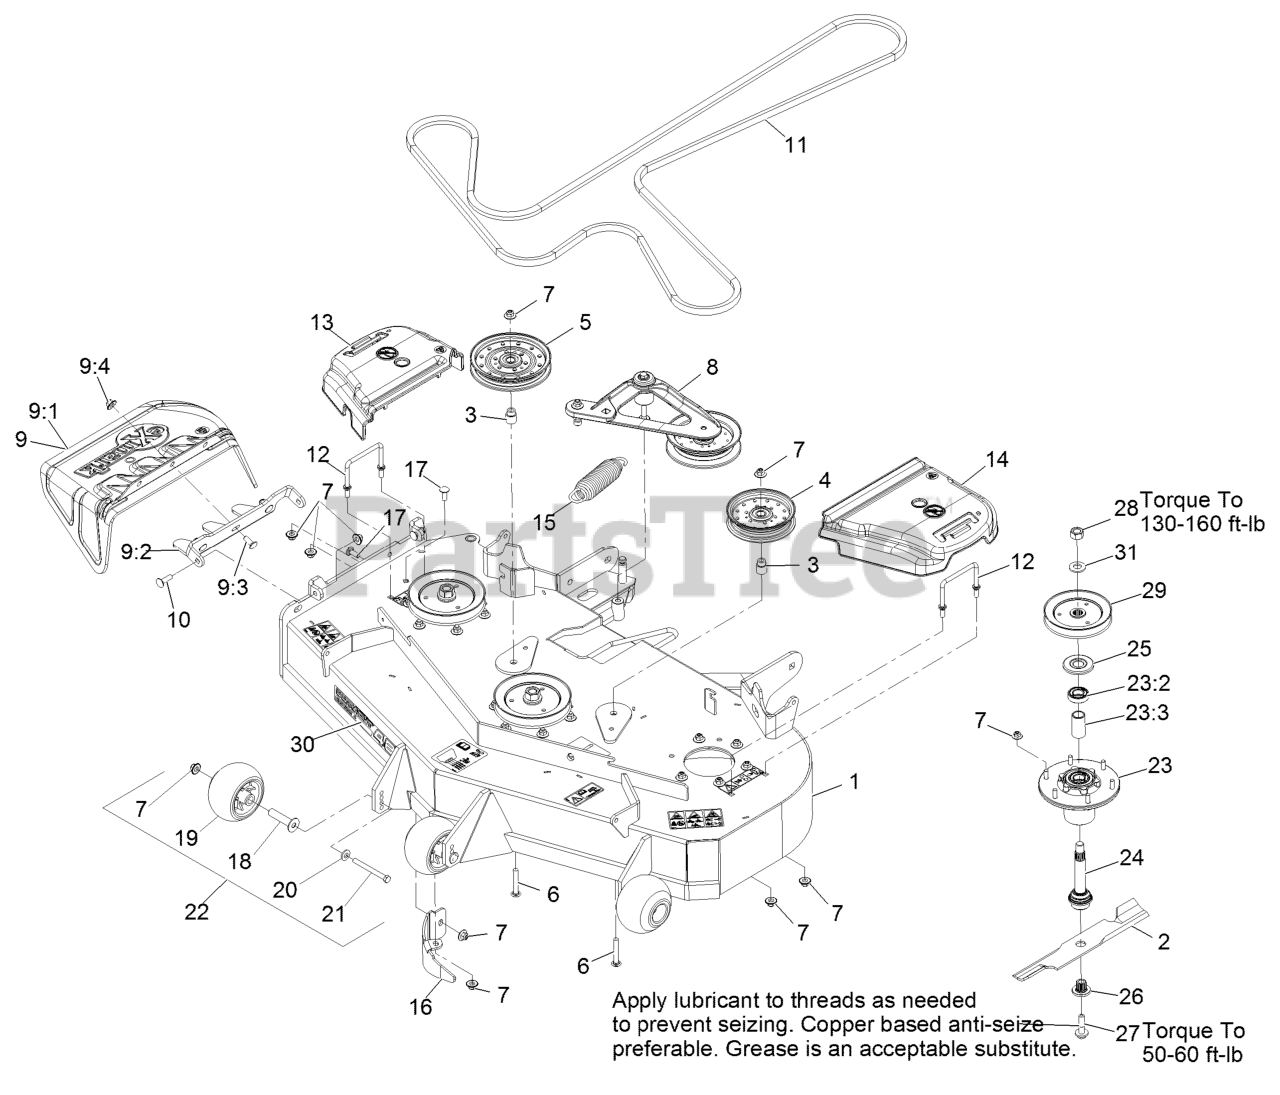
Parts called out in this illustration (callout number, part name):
1	ASM,DECK W/DECALS 48
3	BUSHING-IDLER
6	SCREW-CARR
7	Nut-Nyloc 3/8-16 Flg
8	DECK IDLER ASM
9	ASM,DISCHARGE CHUTE
9:1	CHUTE,DISCHARGE
9:2	BRACKET,DISCHARGE CHUTE
9:3	SCREW-CARR
9:4	Nut-Nyloc 3/8-16 Flg
10	Bolt-Carriage 3/8-16 X 1 1/4
11	BELT
12	WIREFORM-COVER
13	COVER-BELT, RH
14	COVER-BELT, LH
15	SPRING-EXTENSION
16	BAFFLE-DOGLEG,LZS LZX VT4
17	SCREW-CARR
18	AXLE, ROLLER
19	ROLLER-SCALP, ANTI
20	WASHER-BELLEVILLE
21	SCREW-HH 3/8-16 X 3 3/4 GR 8
22	KIT, ANTI-SCALP ROLLER
23	ASM-CUTTER HSG WITH BEARINGS
23:2	BEARING-BALL
23:3	SPACER-BEARING
24	ASM-SPINDLE AND SEAL
25	GUARD,BEARING TOP .989
26	BUSHING,SPLINED
27	SCREW,SEMS 1/2-20 X 2.19
28	NUT-HEX
29	SHEAVE,BLADE DRIVE 5.90
30	Decal, 484
